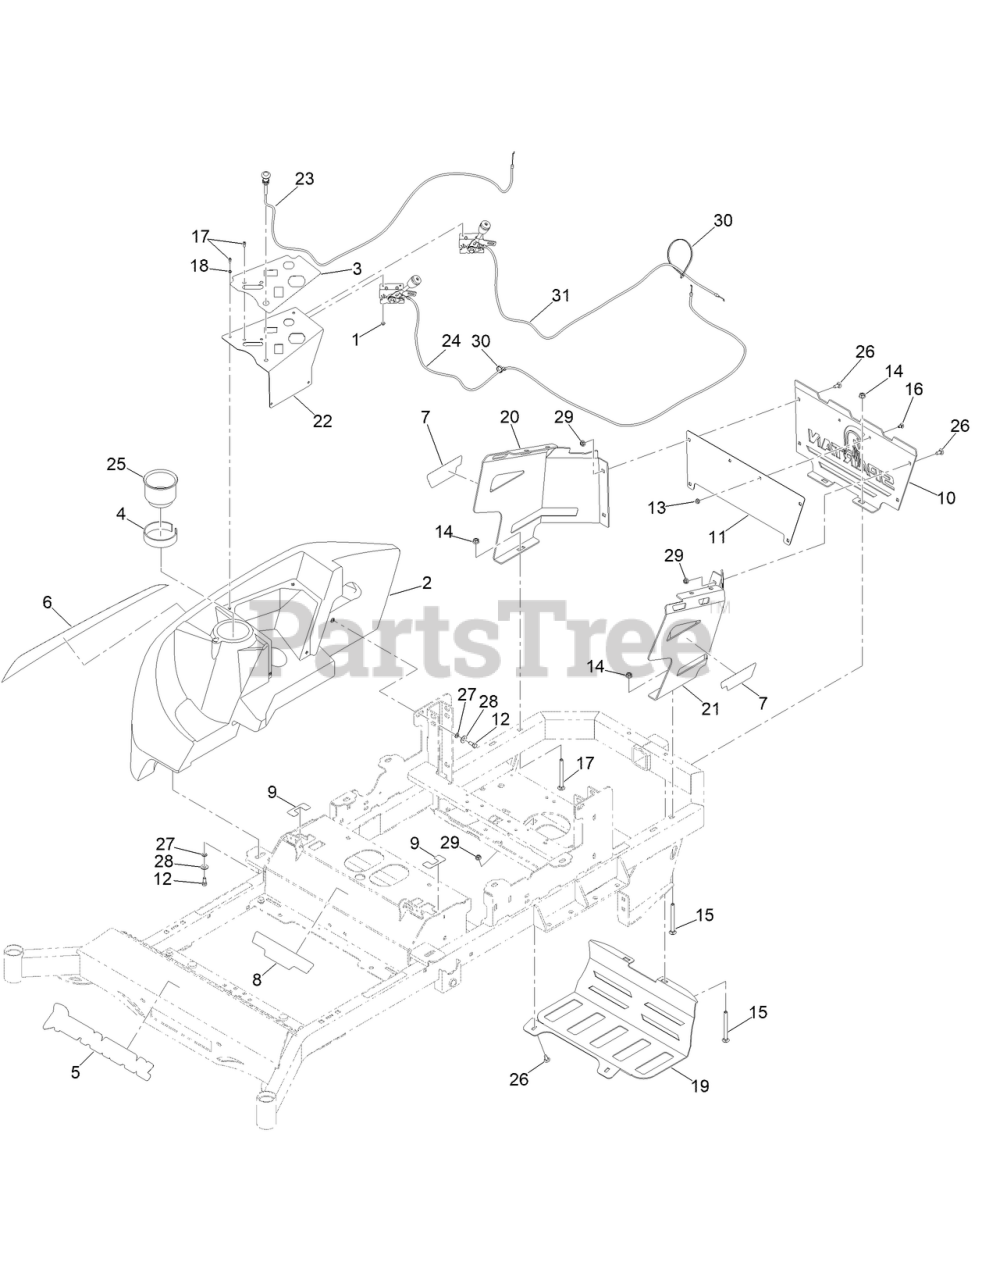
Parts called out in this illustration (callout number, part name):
1	NUT-LOCK
2	CONSOLE W/ CUPHOLDER
3	DECAL-CONTROL PANEL
4	TAPE-FOAM
5	DECAL-SPARTAN, FRONT
6	DECAL-TANK
7	DECAL-MODEL
8	DECAL-RT-HD GT TRAC MODEL
9	DECAL-MOTION CONTROL
10	PLATE - ENGINE COWLING
11	PLATE -BACKER PLATE
12	SCREW-HH
13	1/4-20 HEX FLANGE NUT W/SERR ZINC
15	3/8-16 X 4 CARRIAGE BOLT ZINC
16	1/4-20 X 1/2 CARRIAGE BOLT,YZ
17	10-24 X 1/2 SOCKET C/S 18-8 SS
18	#10 SPLIT LOCKWASHER 18-8 SS
19	MUFFLER GUARD [GRAY]
20	2021 RT/SRT ENGN COWLING RTPAINTED
21	2021 RT/SRT ENGN COWLING LT PAINTED
22	RT 45 KEY MNT
23	MWR CHOKE CABLE ASSM
24	ENVY/FX1000 THROTTLE CABLE
25	CUP HOLDER
26	BOLT-CARR
27	WASHER-LOCK
28	WASHER-FLAT
30	TIE-CABLE
31	MWR THROTTLE CABLE ASSY W / HANDLE
